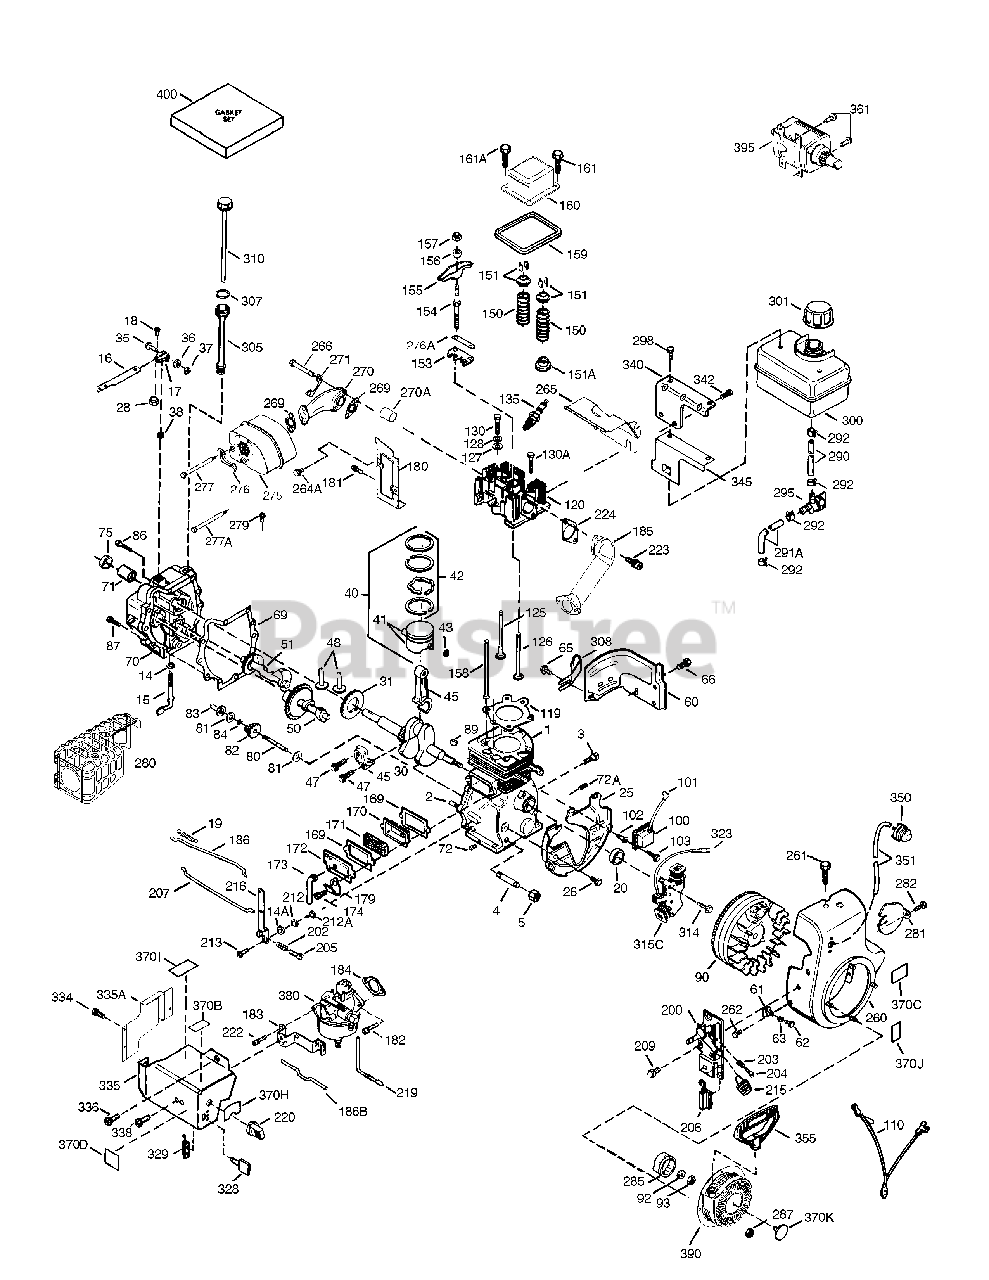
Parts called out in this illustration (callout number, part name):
2	Dowel Pin
3	Screw (1/4-20x1/2")
4	PURCHASE LOCALLY
5	Extension Cap
15	Governor Rod
16	Governor Lever
17	Governor Lever Clamp
18	Screw (T-15)
19	Extension Spring
25	Blower Housing Baffle
26	Screw (1/4-20x19/32")
28	Lock Nut (8-32)
30	Crankshaft
31	Counter Balance Gear
35	Screw (10-32x3/4")
36	Lock Washer
37	Lock Nut (10-32)
38	Retaining Ring
40	Piston, Pin & Ring Set (Std.)
41	Piston & Pin Assy. (Std.)
42	Ring Set (Std.)
43	Piston Pin Retaing Ring
45	Connecting Rod Assy.
47	Connecting Rod Bolt
48	Valve Lifter
51	Counter Balance Weight
60	Blower Housing Extension
65	Screw (10-24x9/16")
66	Screw (T-30)
69	Cylinder Cover Gasket
70	Cylinder Cover
71	Bearing Cover
80	Governor Shaft
82	Governor Gear Assy.
83	Governor Spool
84	Retaining Ring
86	Screw (1/4-20x1-3/16")
87	Screw (1/4-20x1-11/16")
89	Flywheel Key
92	Belleville Washer
93	Flywheel Nut
100	Solid State Ignition
101	Spark Plug Cover
102	Mounting Stud
103	Screw (T-15)
110	Wire Assy.
119	Cylinder Head Gasket
120	Cylinder Head
125	Exhaust Valve (Std.)
126	Intake Valve (Std.)
128	Belleville Washer
130	Screw (5/16-18x2-1/2")
135	Spark Plug
150	Valve Spring
151	Valve Spring Keeper
151A	Intake Valve Seal
153	Push Rod Guide
154	Rocker Arm Stud
155	Rocker Arm
156	Rocker Arm Bearing
159	Rocker Arm Cover Gasket
160	Rocker Arm Cover
161	Screw (T-30)
161A	Valve Cover Mounting Stud
163	Lock Washers
169	Valve Cover Gasket
170	Breather Body
171	Breather Element
172	Valve Cover
173	Breather Tube
174	Screw (10-24x1/2")
180	Blower Housing Extension
182	Screw (1/4-20x27/32")
183	Choke Bracket
184	Carb Intake Pipe Gasket
185	Intake Pipe
186	Governor Link
186B	Choke Spring
200	Control Bracket
202	Compression Spring
203	Compression Spring
204	Screw (T-10)
205	Screw (T-10)
207	Throttle Link
209	Screw (10-32x1/2")
213	Screw (10-32x5/8")
215	Control Knob
216	R.P.M. Adjusting Lever
219	Choke Rod
220	Choke Knob
222	Screw (10-32x1/2")
223	Screw (T-30)
224	Intake Pipe Gasket
260	Blower Housing
261	Screw (1/4-20x5/8")
262	Screw (5/16-18x9/16")
265	Cylinder Head Cover
266	Screw (5/16-18x1-9/32")
269	Exhaust Gaskets
270	Exhaust Manifold
270A	Exhaust Port Liner
271	Locking Plate
276	Locking Plate
276A	Screw (1/4-20x4-19/32")
277	Screw (5/16-18x4-4-1/2")
279	Screw (10-32x5/16")
280	Heat Shield
285	Starter Cup
287	Nut & Lock Washer (1/4-28)
290	Fuel Line
292	Fuel Line Clamp
298	Screw (1/4-15x3/4")
305	Oil Fill Tube
308	Fill Tube Clip
314	Screw (1/4-20x3/4")
328	Ignition Keys
335	Front Carburetor Cover
335A	Carburetor Cover
338	Screw (10-32x1/2")
342	Screw (5/16-18x7/8")
345	Heat Baffle
350	Primer Assy.
351	Primer Line
355	Starter Handle
361	Screw (T-30)
370B	Control Decal
370C	Primer Decal
370D	Warning Decal
370I	Warning Decal
370K	Starter Decal
380	Carburetor
390	Recoil Starter Assy.
395	Electric Starter Motor
400	Gasket Set
